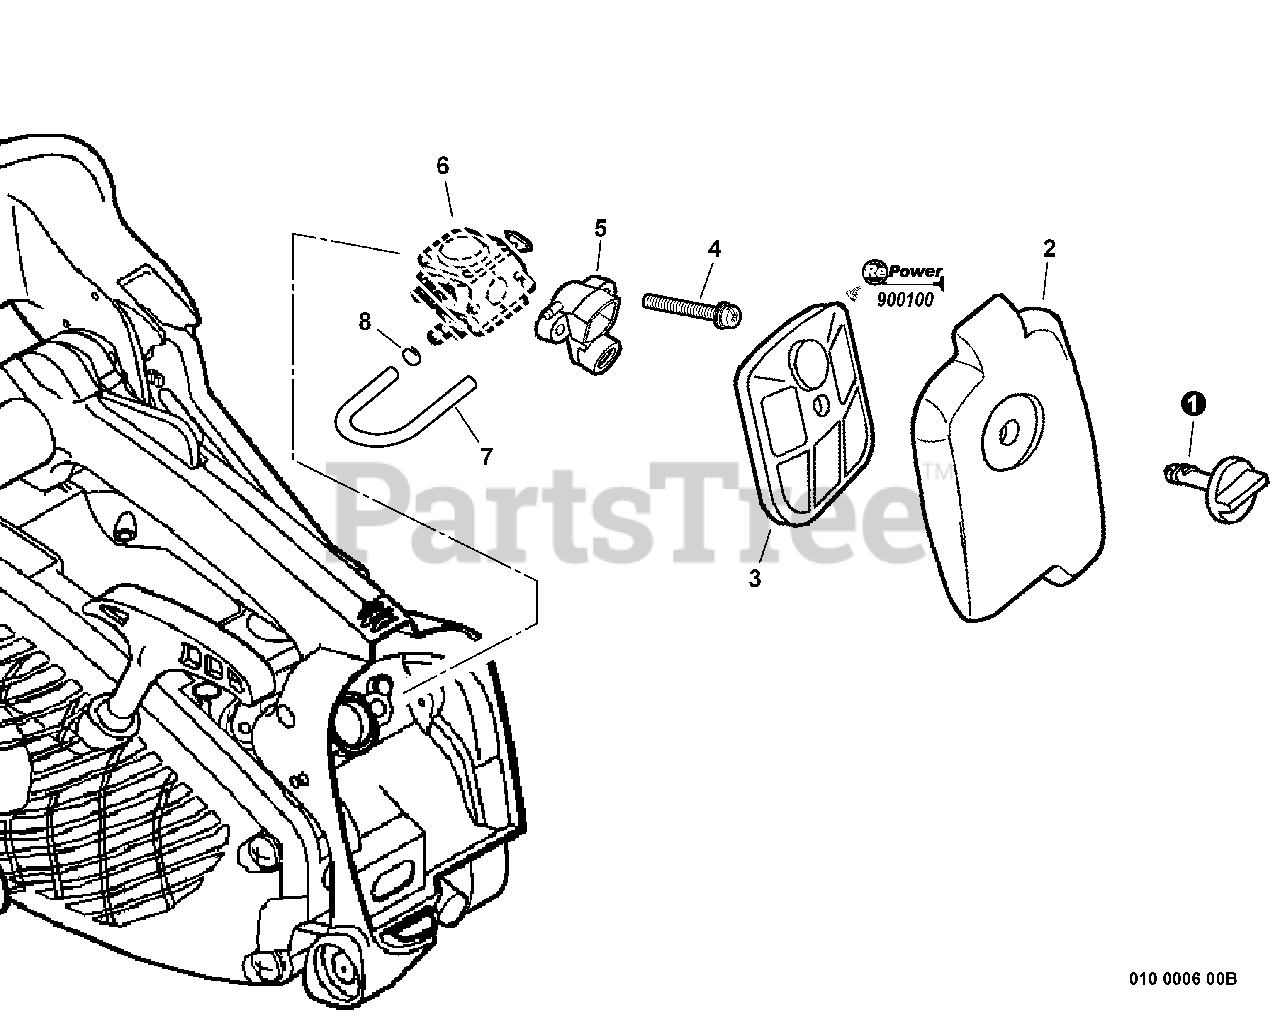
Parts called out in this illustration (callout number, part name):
1	THUMBSCREW
2	COVER, AIR FILTER
3	FILTER, AIR
4	SCREW - 5X50
5	MOUNT, AIR FILTER
6	CARBURETOR
7	PIPE
8	CLIP - 6
9	RePower TUNE-UP KIT
